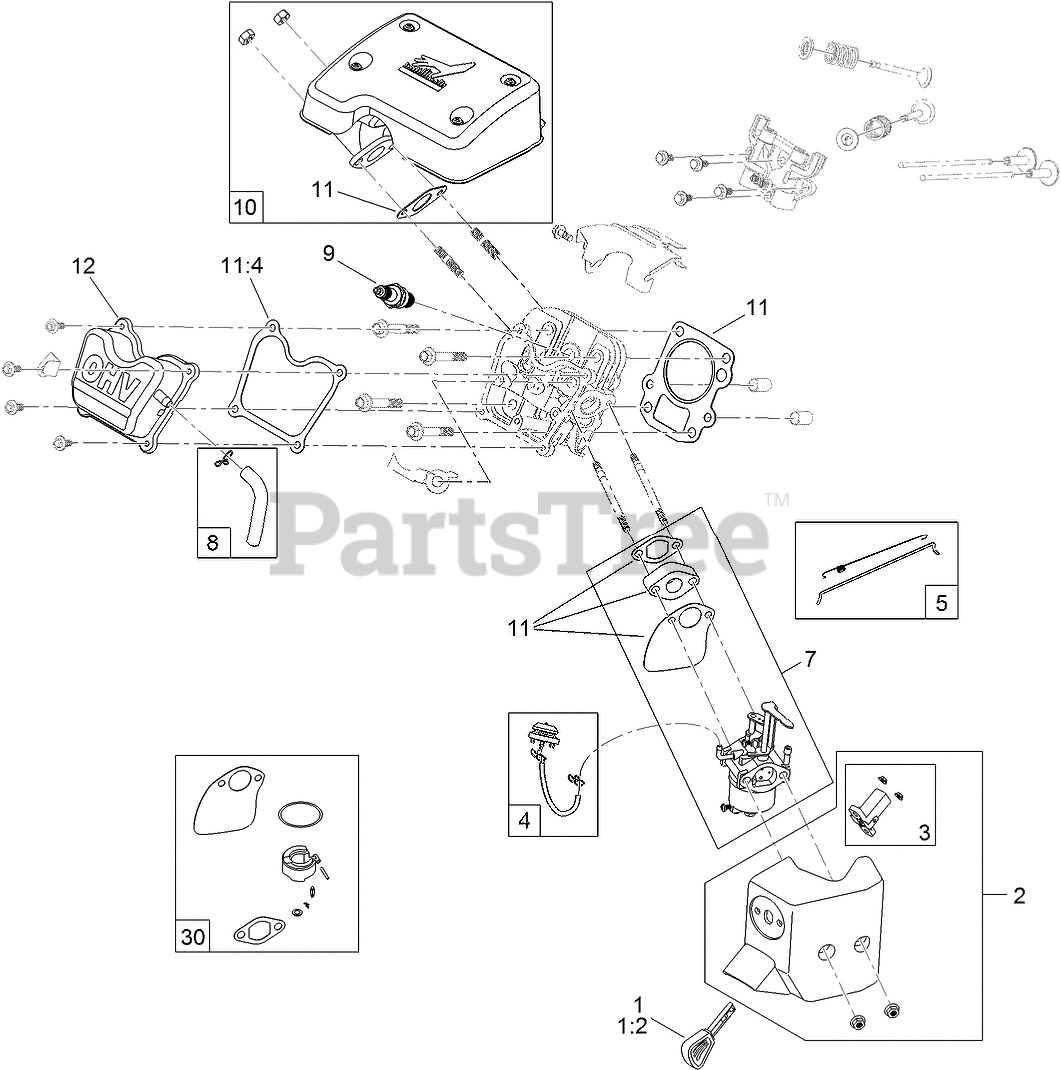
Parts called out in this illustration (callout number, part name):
1	KEY AND LANYARD KIT
2	HEATER BOX KIT
3	SWITCH KIT
4	PRIMER BULB KIT
5	GOVERNOR KIT
7	COMPLETE CARB SERVICE KIT
8	BREATHER TUBE KIT
9	SPARK PLUG
10	MUFFLER KIT
11	GASKET, SEAL AND O-RING KIT
11:4	GASKET-COVER, VALVE
12	VALVE COVER ASM
30	CARB FLOAT AND NEEDLE KIT
